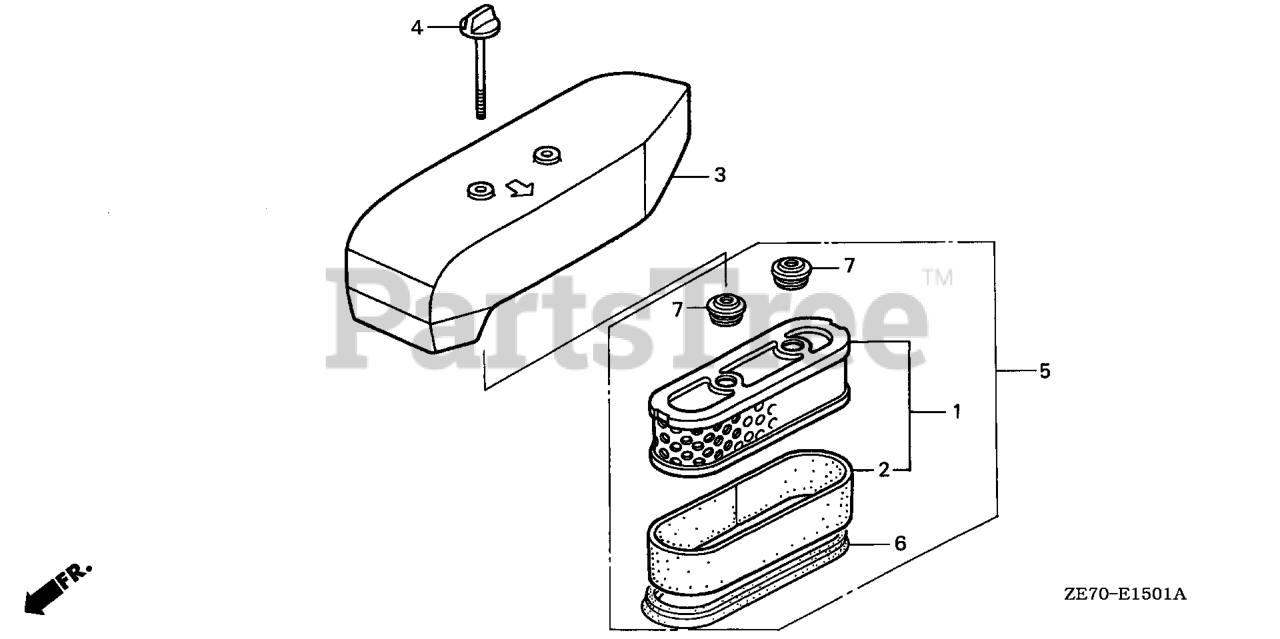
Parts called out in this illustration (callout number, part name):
2	FILTER (OUTER)
3	COVER, AIR CLEANER *NH1* (BLACK)
4	BOLT, AIR CLEANER (6X73)
5	ELEMENT, AIR CLEANER (TOYO)
6	GASKET, ELEMENT
7	GROMMET, AIR CLEANER
